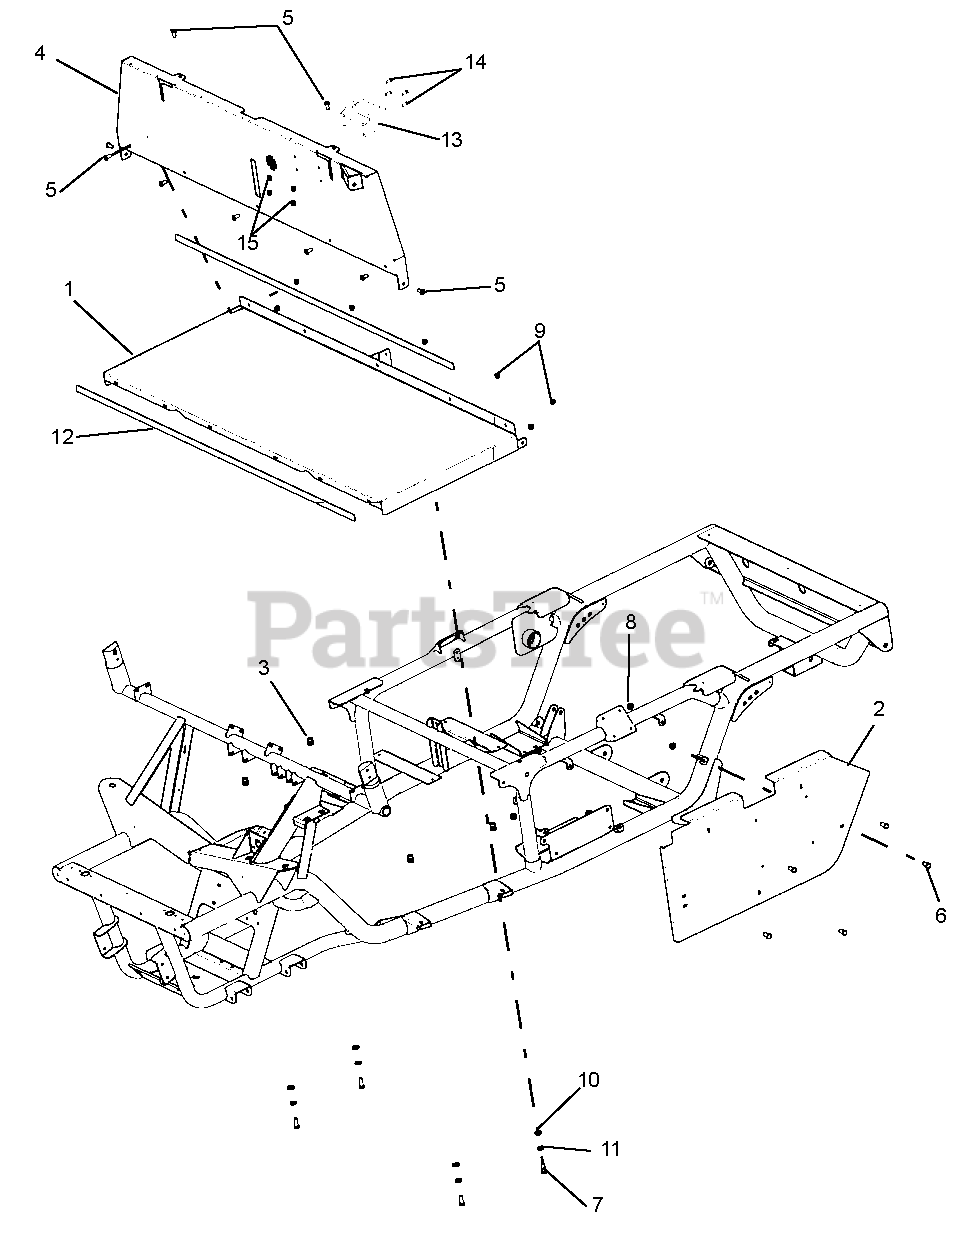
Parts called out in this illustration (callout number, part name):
1	FLOOR WIDE WELDMENT
2	SIDE PANEL, WIDE
3	NUTZERT, 5/16-18 X .667 HEX
4	KICK PANEL WLDMNT
5	SCREW, MACHINE .25-20 X .75 TXTR YWZC
6	BOLT, HEX 5/16-18 X 3/4 GR5 YWZC
7	BOLT, HEX 5/16-18 X 1 GR5 YWZC
8	NUT, HEX TOP LOCK FLANGE .312-18YWZC
9	NUT, LOCKING TOP FLANGE 1/4-20 YWZC
10	WASHER, FLAT 5/16 HARDENED ASTMF436
11	WASHER, LOCK SPRING 5/16 YWZC
12	FOAM RUBBER 3/16 X 3/4 THK WITH PSA 52.5" Lg.
13	BRACKET, MODULE EPA FUSE/RELAY
14	TTHMS 1/4-20 X 3/4 YWZC
15	NUT, HEX FLANGE TL 1/4-20 YWZC
